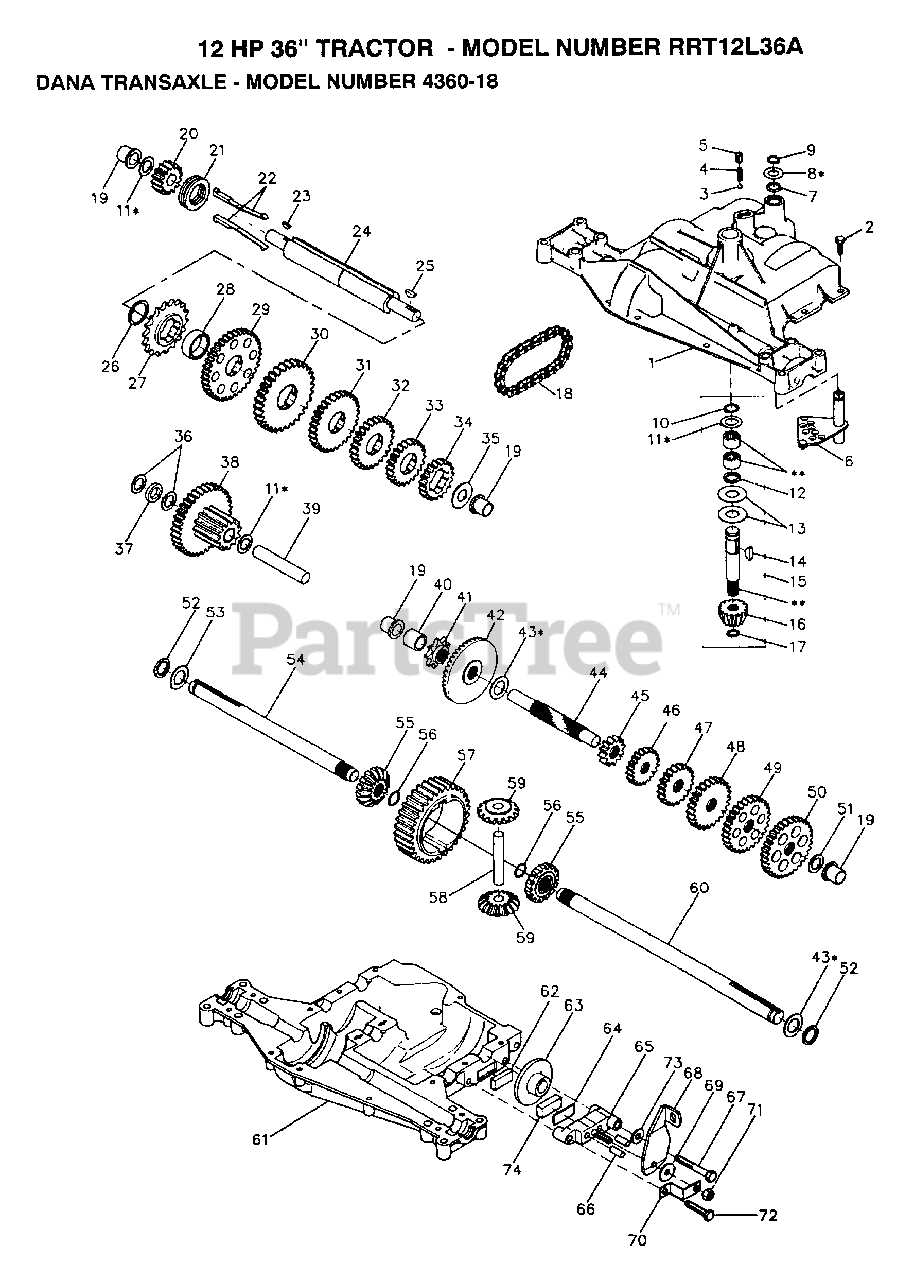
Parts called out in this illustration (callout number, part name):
1	HOUSING UPPER
3	BALL DETENT
4	SPRING, DETENT
5	SCREW, SET
6	ASSY SHIFTER
8	WASHER PLAIN
9	RING RETAINING
10	RING RETAINING
11	WASHER PLAIN
13	WASHER, PLAIN .632 X 1.38 X .046
14	KEY WOODRUFF #9
15	ASSY KIT INPUT SHAFT
16	PINION, BEVEL, 14 TEETH
17	RING, RETAINING
18	CHAIN, 24 PITCHES
19	BEARING, FLANGE
20	GEAR SPUR, 14 TEETH
21	COLLAR CLUTCH
22	KEY CLUTCH
23	KEY WOODRUFF #3
24	SHAFT INTERMEDIATE
25	KEY, WOODRUFF, #61
26	RING, RETAINING
27	SPROCKET, 18 TEETH
29	GEAR, SPUR, 37 TEETH
30	GEAR, SPUR, 35 TEETH
31	GEAR, SPUR, 30 TEETH
32	GEAR, SPUR, 25 TEETH
33	GEAR, SPUR, 22 TEETH
35	WASHER, PLAIN .640 X 1.37 X .061
36	WASHER, PLAIN .632 X 1.00 X .026
37	SPACER .630 X 1.00 X .169
38	ASSY GEAR COMB 12&35 TEETH
39	SHAFT IDLER
40	SPACER .635 X .875 X .755
41	SPROCKET, 9 TEETH
42	GEAR, BEVEL, 42 TEETH
43	WASHER PLAIN
44	SHAFT, DRIVE
45	GEAR, SPUR, 12 TEETH
46	GEAR SPUR, 15 TEETH
47	GEAR, SPUR, 20 TEETH
48	GEAR, SPUR, 25 TEETH
49	GEAR, SPUR, 28 TEETH
50	GEAR, SPUR, 31 TEETH
51	WASHER, PLAIN .632 X 1.00 X .060
53	WASHER PLAIN
54	AXLE LEFT HAND
55	GEAR, MITER, 15 TEETH
56	RING, RETAINING
57	GEAR, SPUR, 32 TEETH
58	SHAFT, CROSS
59	GEAR, MITER, 15 TEETH
60	AXLE RIGHT HAND
61	HOUSING LOWER
62	PUCK, FRICTION
63	DISC, BRAKE
65	JAW, BRAKE
66	PIN, DOWEL
67	SCREW TAPPING
68	LEVER, ACTUATING
69	WASHER, PLAIN .321 X 1.00 X .055
70	BRACKET, ANTI-ROTATION
71	LOCKNUT 5/16-24
72	SCREW TAPPING
73	WASHER PLAIN
74	PUCK, FRICTION
